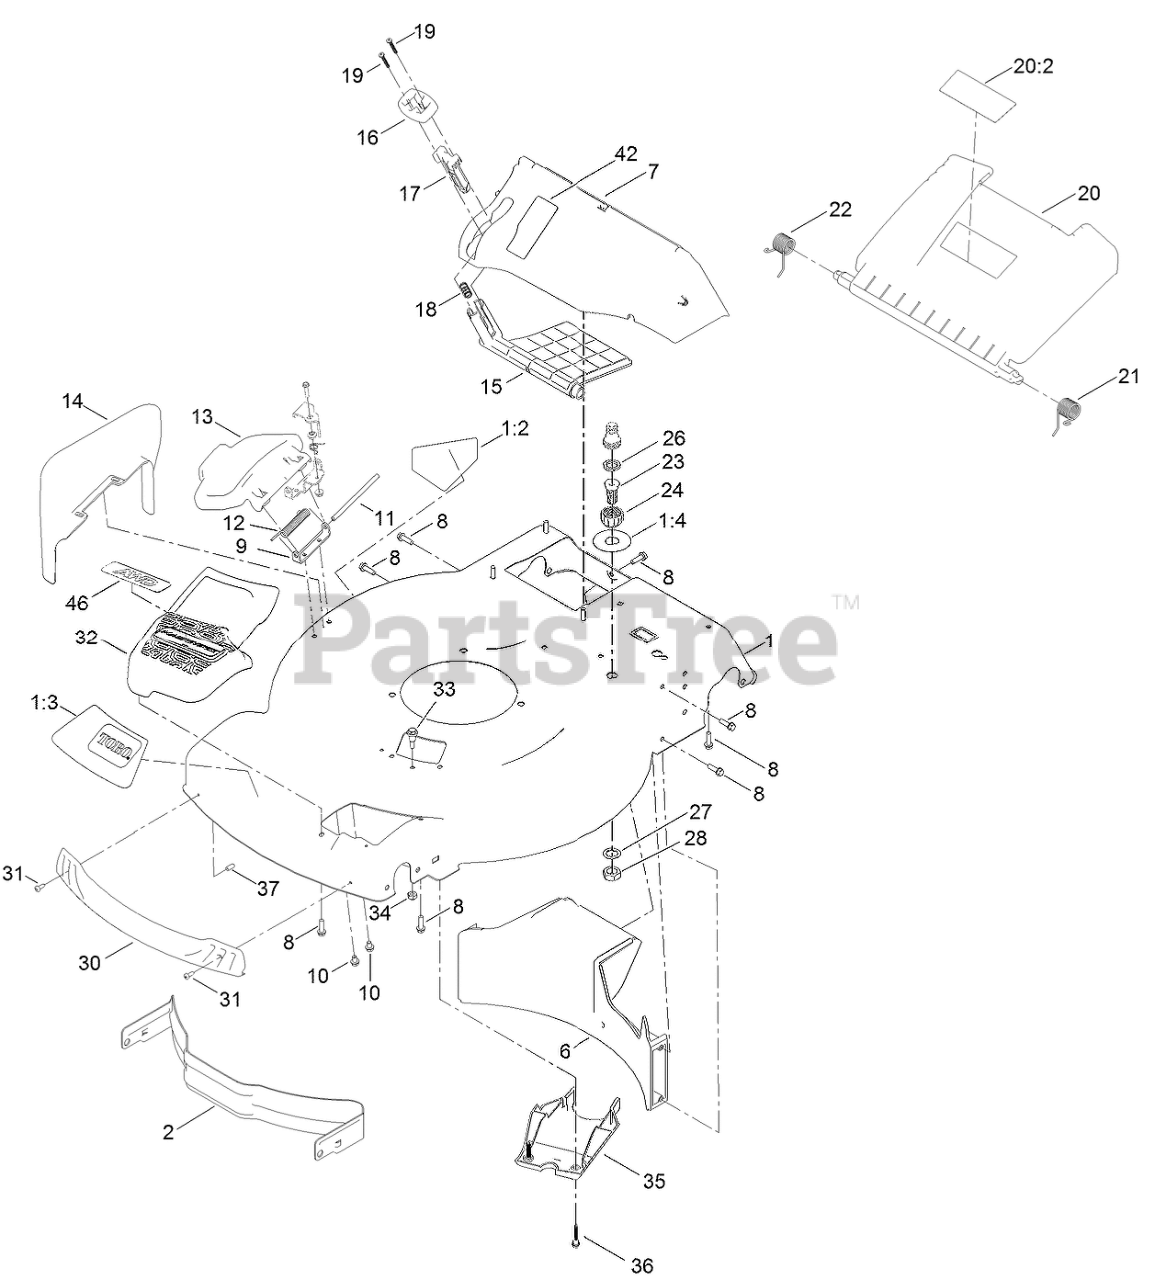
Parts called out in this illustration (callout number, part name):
1	HOUSING ASM
1:2	DECAL-DANGER
1:3	DECAL-DECK
1:4	DECAL-QUICK WASH
2	BAFFLE-FRONT
6	BAFFLE-REAR
7	CHUTE-RECYCLE
8	SCREW-HWH
9	BRACKET-COVER
10	SCREW-HWH
12	SPRING-TORSION
13	DEFLECTOR-SIDE
14	CHUTE-DISCHARGE, SIDE
15	DEFLECTOR-RECYCLE
16	KNOB-RECYCLE
17	LATCH-RECYCLE
18	SPRING-COMPRESSION
19	SCREW-PPH
20	REAR DOOR ASM
20:2	DECAL-WARNING
21	SPRING-TORSION
22	SPRING-TORSION
23	PORT-WASHOUT
24	COUPLING-HOSE, WASHOUT PORT
26	WASHER-SEAL, WASHOUT PORT
27	WASHER-LOCK
28	NUT-JAM
30	BUMPER
31	SCREW-FORMING, THREAD
32	COVER-BELT, FRONT
33	BOLT-SHOULDER
34	NUT-LOCK, NI
35	COVER-BELT, FRONT
36	SCREW-SHOULDER, HHF
37	CAP-PLUG
46	DECAL-BELT COVER, POWEREVERSE
